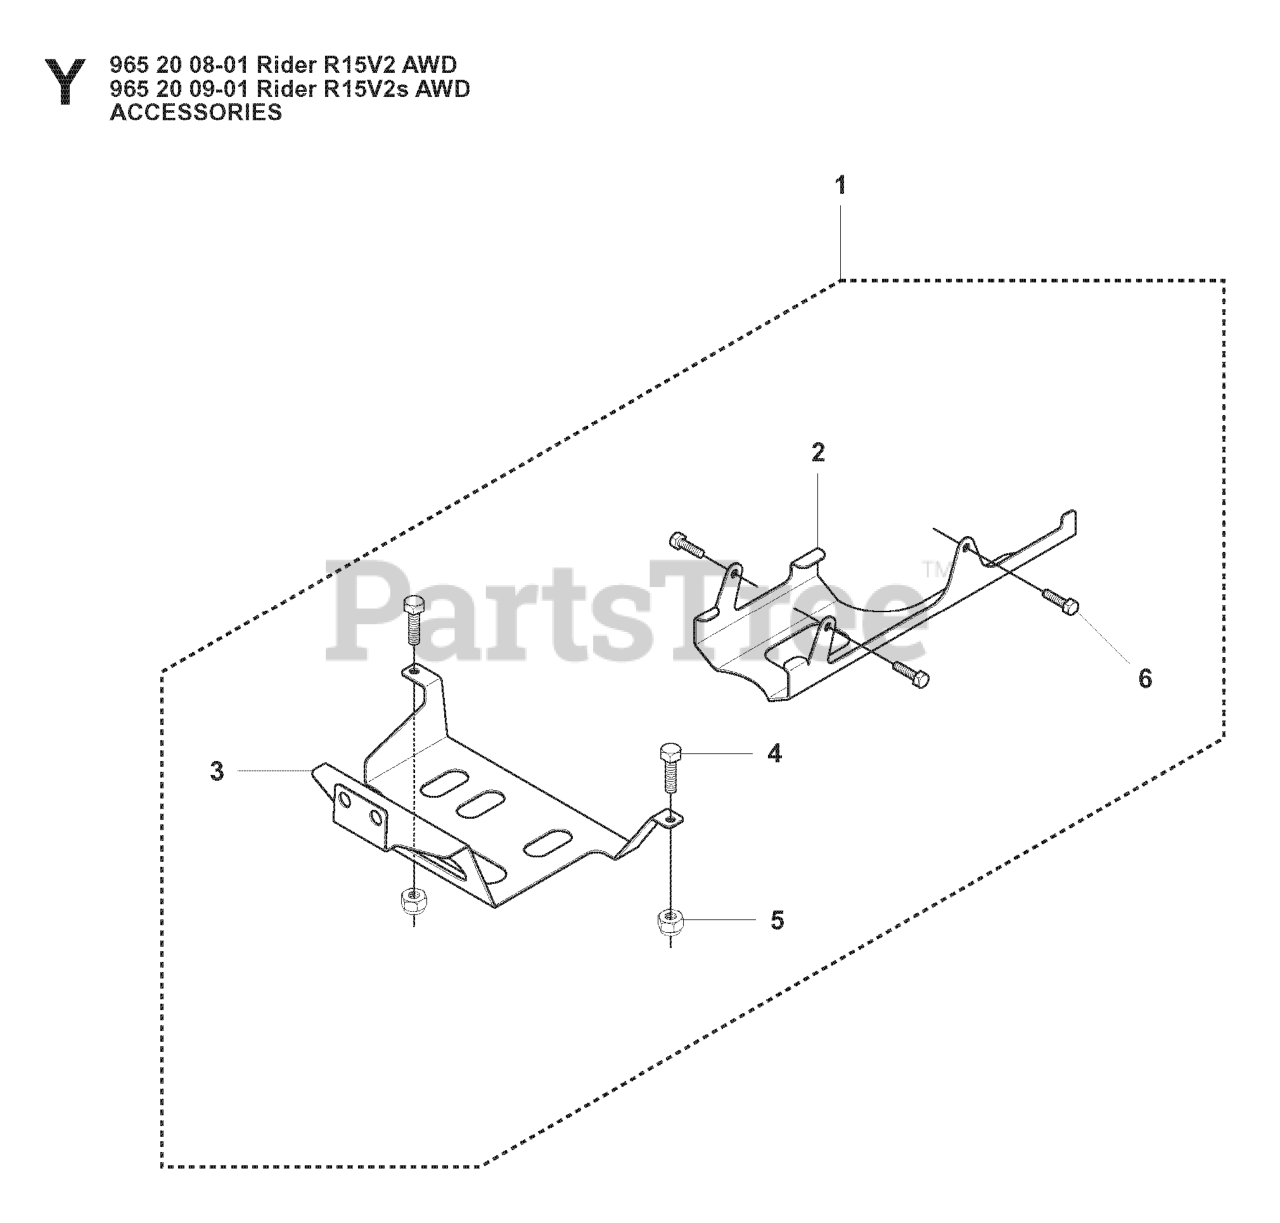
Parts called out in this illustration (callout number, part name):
1	AXLE PROTECTION KIT (R322T)
3	RP PROTECTION PLATE REAR
5	LOCKNUT M8
6	BOLT FLANGE - M8X16
